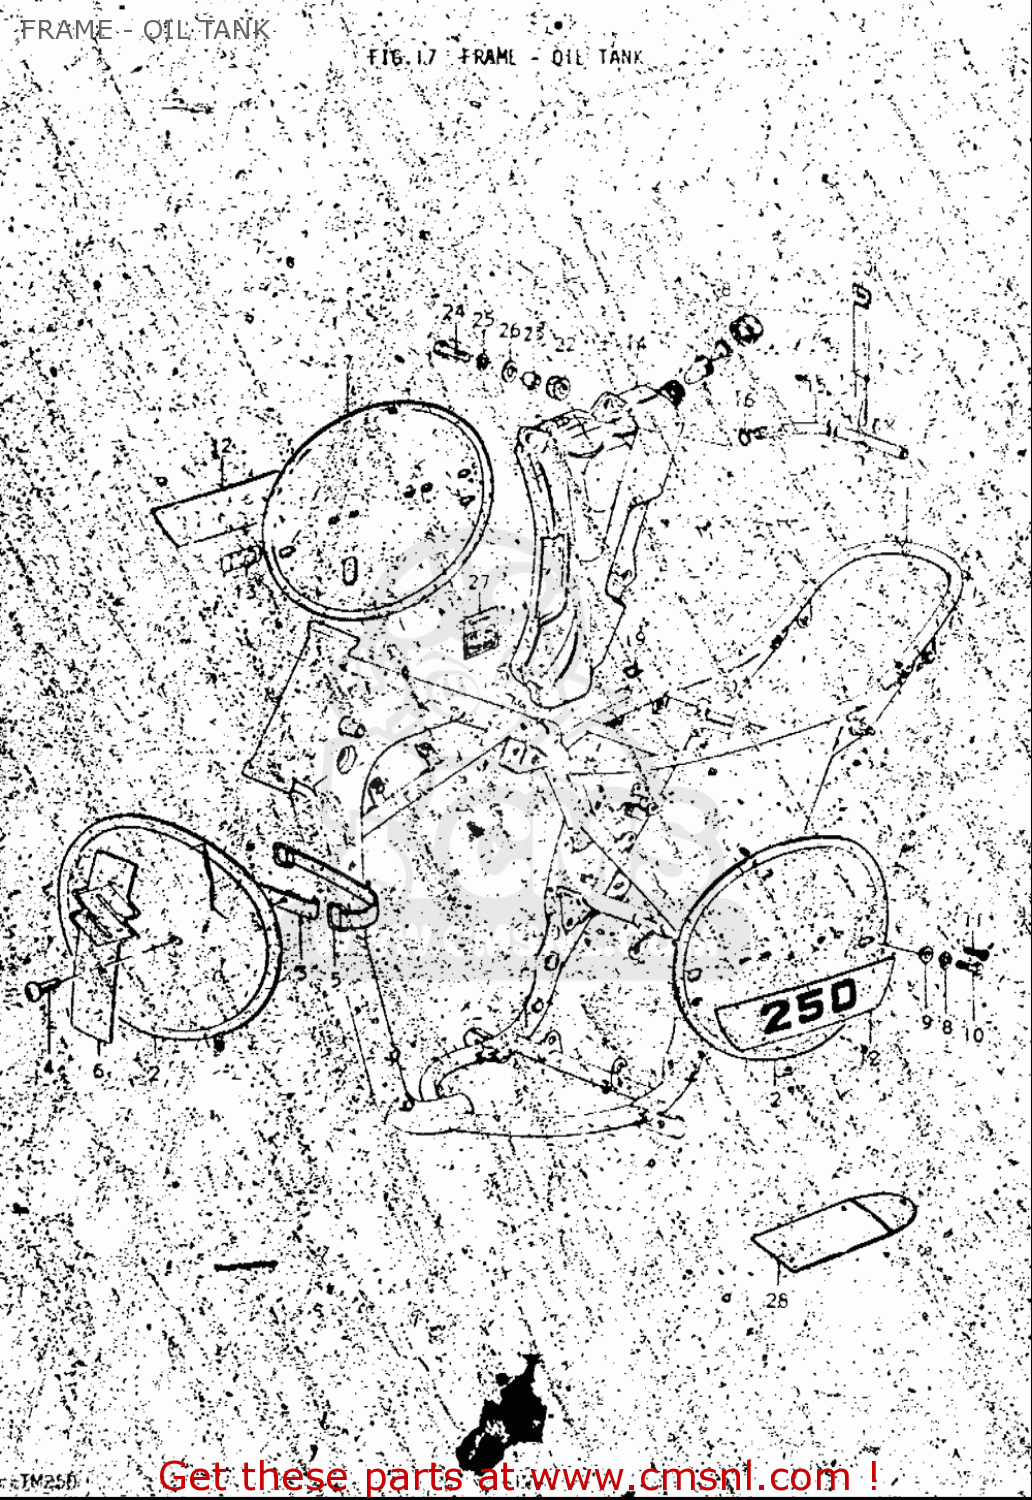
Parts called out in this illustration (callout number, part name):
4	SCREW 6X12
5	BAND
8	WASHER,LOCK
9	WASHER
10	BOLT
11	SCREW 6X12
13	EMBLEM,CCIS
15	HOSE(5X8X2000)
16	CLIP
17	CAP, OIL TANK
18	GASKET,OIL TANK CAP (NAS)
19	CLIP
20	CLAMP
21	GASKET,OIL TANK CAP (NAS)
22	CUSHION
23	SPACER(6.5X10X10)
24	BOLT
25	WASHER,LOCK
26	WASHER(6.5X20X1.2)
